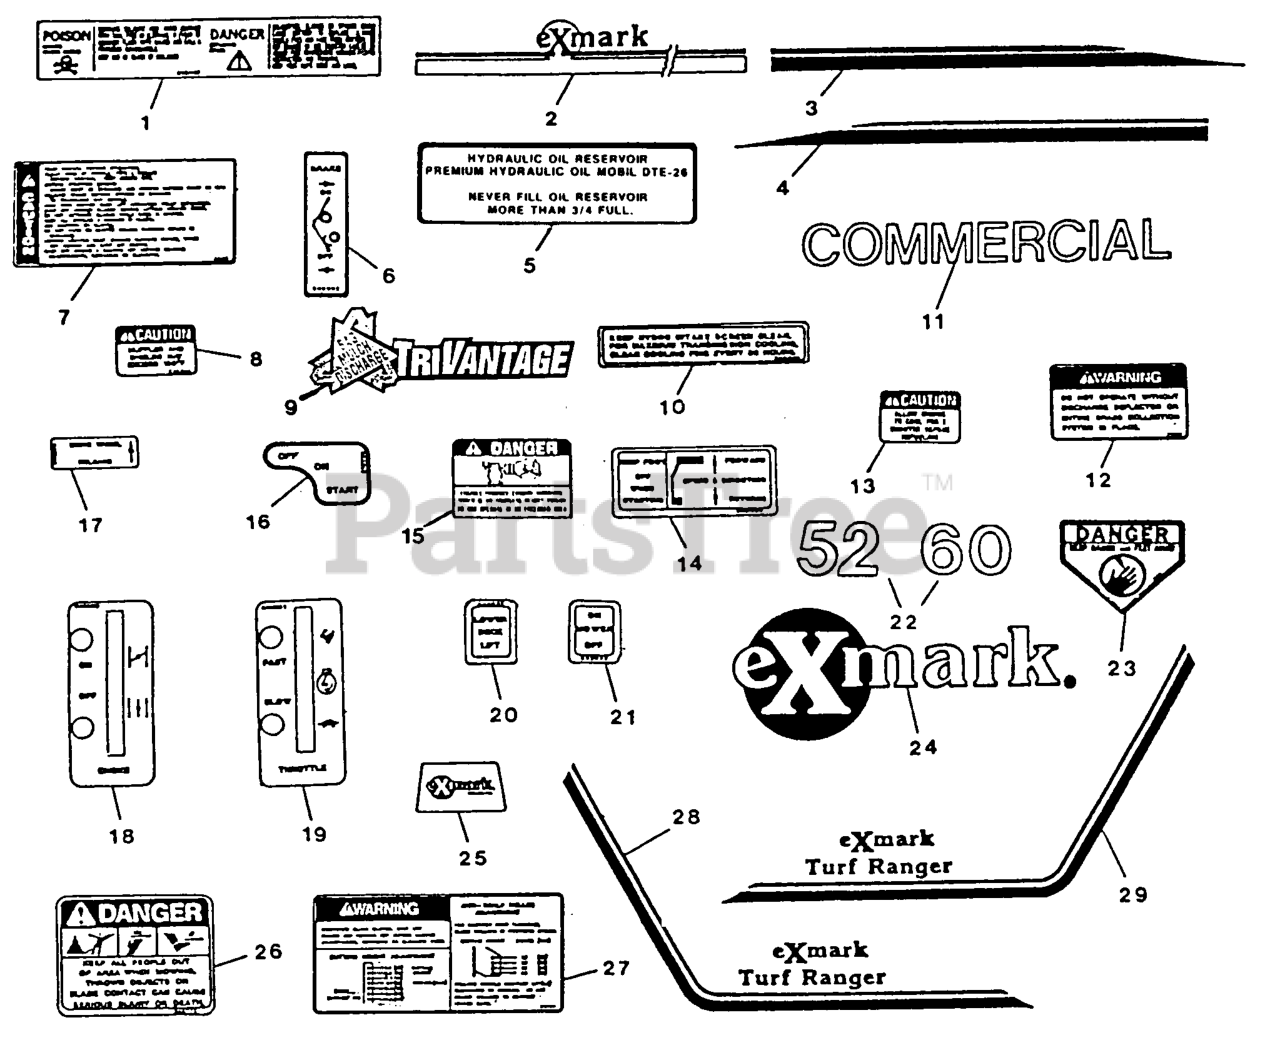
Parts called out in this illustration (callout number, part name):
1	DECAL-BATTERY
10	DECAL,INTAKE
12	DECAL-WARNING, DISCHARGE
14	DECAL,FOOT PEDAL
20	DECAL-DECK LIFT
21	DECAL-MOWER SWITCH
23	DECAL-DANGER
26	DECAL-DANGER
